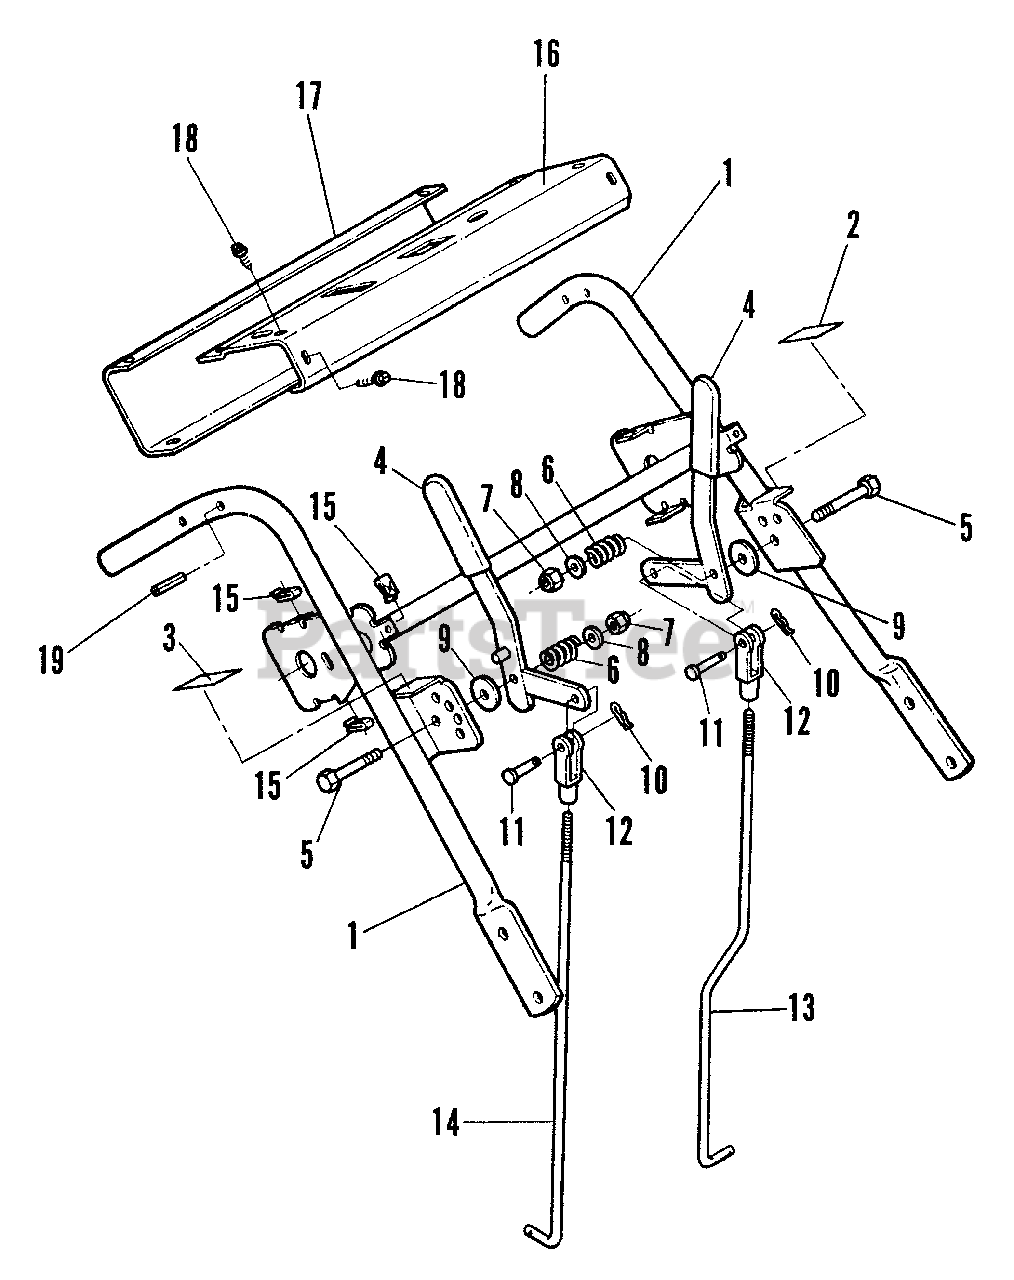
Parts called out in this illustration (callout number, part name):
1	WELDMENT, Upper Handle
2	DECAL, Blade
3	DECAL, Ground Speed
4	LEVER, Control w/Grip Assembly
5	SCREW, 3/8-16 x 2" Hex Head Cap, Grade 5
6	SPRING, Compression
7	NUT, 3/8-16 Hex Nyloc
8	WASHER, 3/8" Standard Flat
9	WASHER, Spacer
10	HAIRPIN, #2
11	PIN, 5/16 Clevis
13	LINKAGE, Blade
14	LINKAGE, Ground Speed
15	NUT, #10-24 Clip
16	PANEL, Control w/Decals
17	COVER, Bottom w/Decal
18	SCREW, #10-24 x 5/8" Pan Head
19	PIN, 5/16 x 1-1/8" Roll
